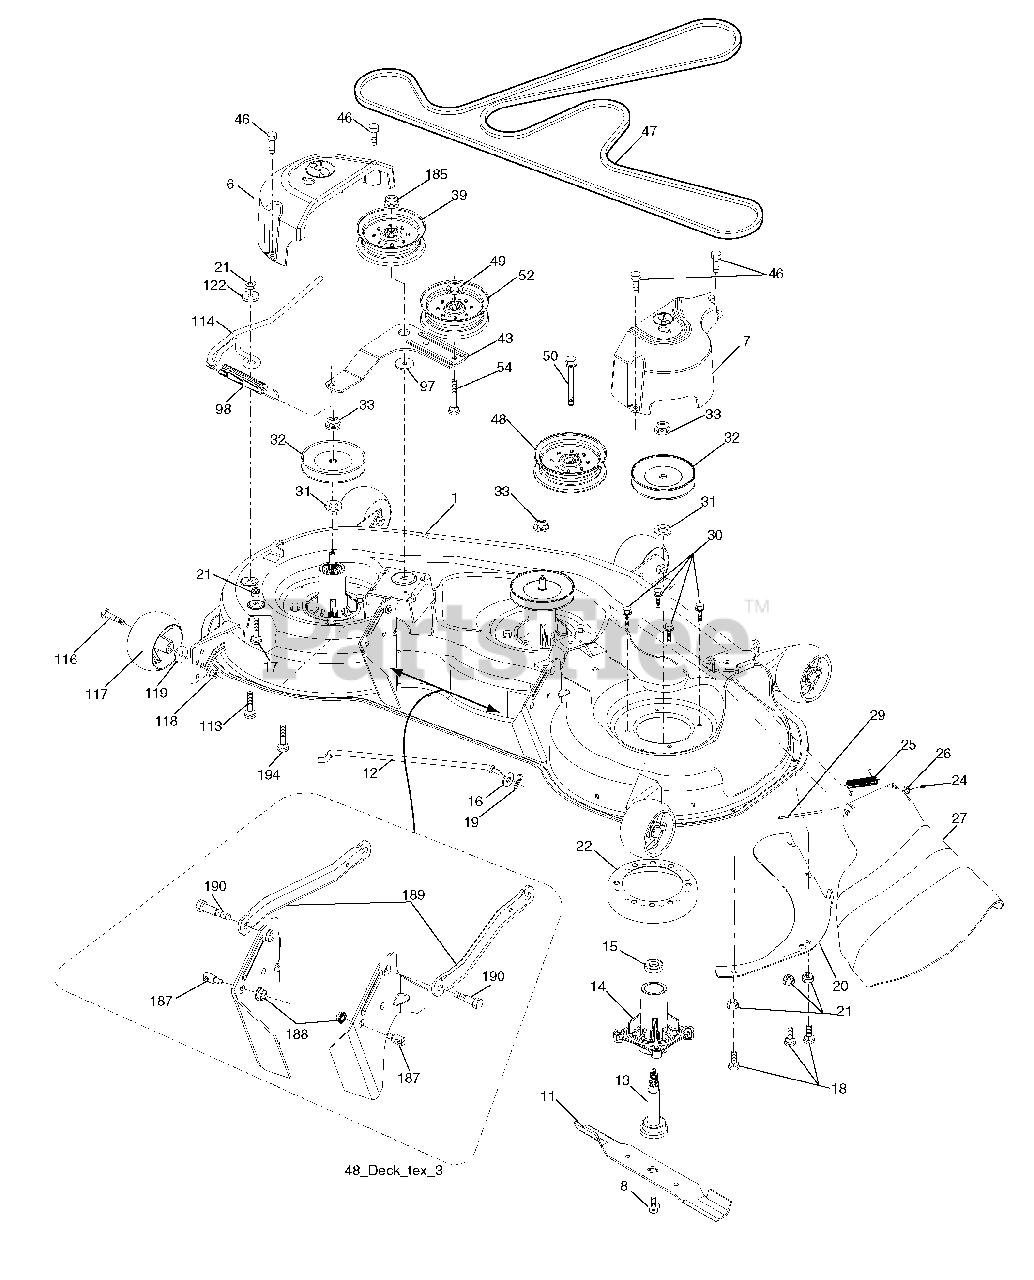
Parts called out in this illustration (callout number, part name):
1	Deck Weldment Mower
6	Cover Mandrel LH
7	Cover Mandrel RH
8	Bolt 7/16 Asm. Blade
11	Blade High Lift
11	Blade Mulching
12	Rod Anti-Sway
13	Shaft Asm. w/Lower Bearing
14	Housing, Mandrel
15	Bearing, Ball, Mandrel
16	Washer 13/23 x 13/16 x 1 2Ga.
17	Bolt Carr. 5/16-18 x 5/8
18	Bolt RdHd 5/16-18 unc x 5/8
19	Pin Cotter 5/16 Bowtie Lock
20	Baffl e Vortex
21	Nut, Crownlock 5/16-18 unc
22	Stripper Mandrel Deck
24	Cap Sleeve
25	Spring, Torsion
26	Nut, Push
27	Defl ector Shield
29	Rod, Hinge
30	Screw, Thdroll Washer Head
31	Washer, Spacer Mower Vented
32	Pulley, Mandrel
33	Nut, Flg. Top Lock
39	Pulley, Idler, Stationary
43	Arm, Idler
46	Screw, Thdroll. 1/4-20 x 5/8
47	Belt Drive Deck
48	Pulley Idler Primary
49	Nut, Lock Flg. 3/8-16 unc
50	Screw 3/8-16 x 1-1/4 unc
52	Pulley Idler
54	Bolt Carriage 3/8-16 x 1-1/2 Gr.5
97	Washer Hardened
98	Spring Drive
113	Bolt Rdhd Sqnk 5/16-18 x 3/4
114	Rod Tension Relief
116	Bolt, Shoulder
117	Gauge Wheel
118	Nut Centerlock 3/8-16 UNC
119	Washer 3/8 x 7/8 x 14 Ga.
120	Washer 13/32 x 1-1/4 x 12 Ga.
122	Bushing Tension Relief
185	Nut Lock Flange 7/16-14 Gr. 5
187	Stud Fastener w/"D" Anti-Rotation
188	Nut Lock Hex Flange
189	Arm Susp. Mower Rear
190	Bolt Shoulder
194	Bolt Carr Sqnk 3/8-16 x 2-1/4
194	Mandrel Asm. Service
194	Replacement Mower, Complete
